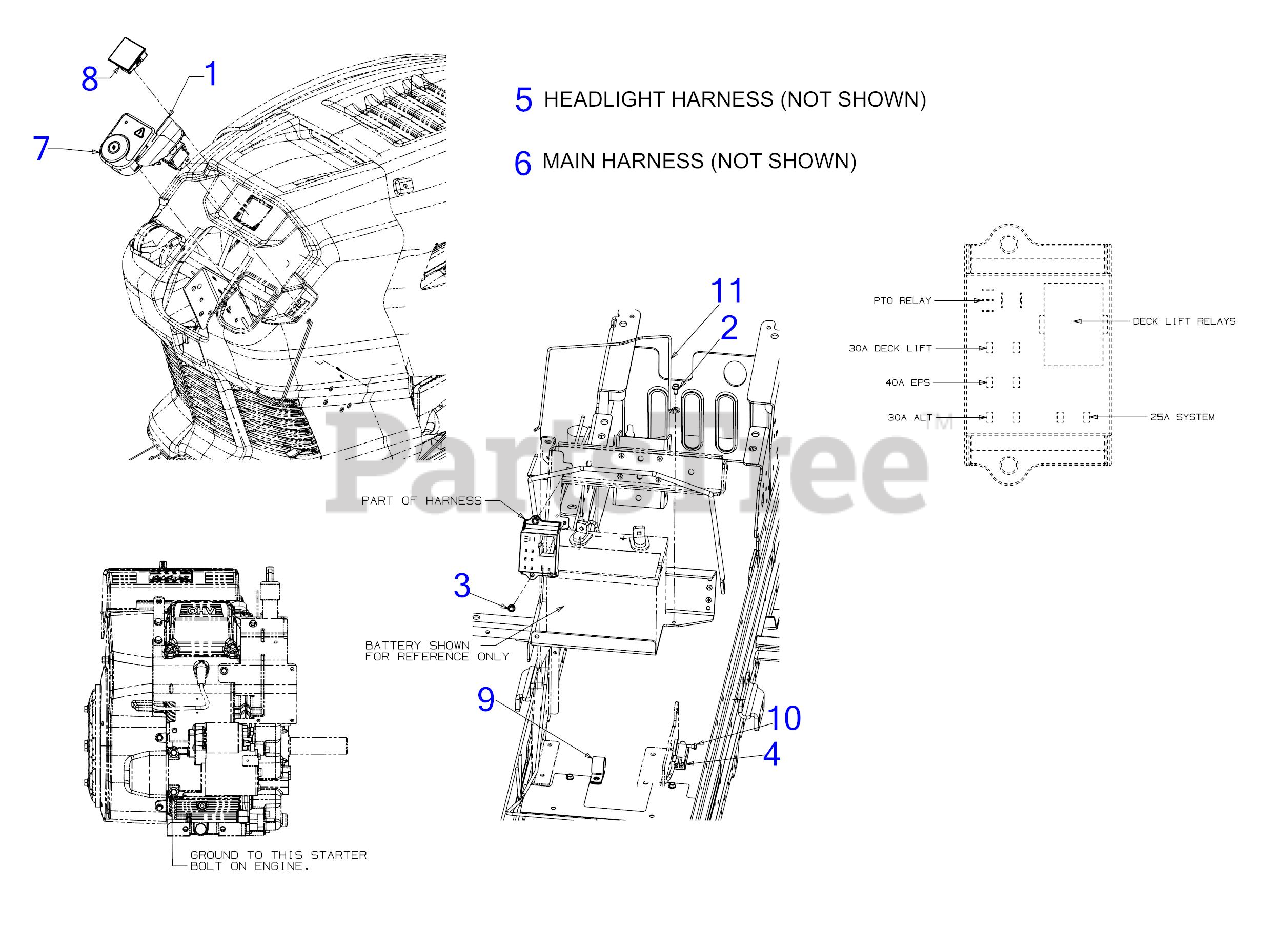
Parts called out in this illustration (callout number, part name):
1	PTO SWITCH ASSEMBLY
2	SCREW 1/4-20 X.500
3	SCREW 1/4-20 x .750
4	INTERLOCK SWITCH (NO/NC)
5	HEADLIGHT HARNESS ASSEMBLY
6	MAIN EPS HARNESS ASSEMBLY
7	IGNITION SWITCH MODULE
8	HOUR/SVC METER
9	HOSE CLAMP 1.0"
10	SHOULDER SCREW
11	BATTERY STRAP
